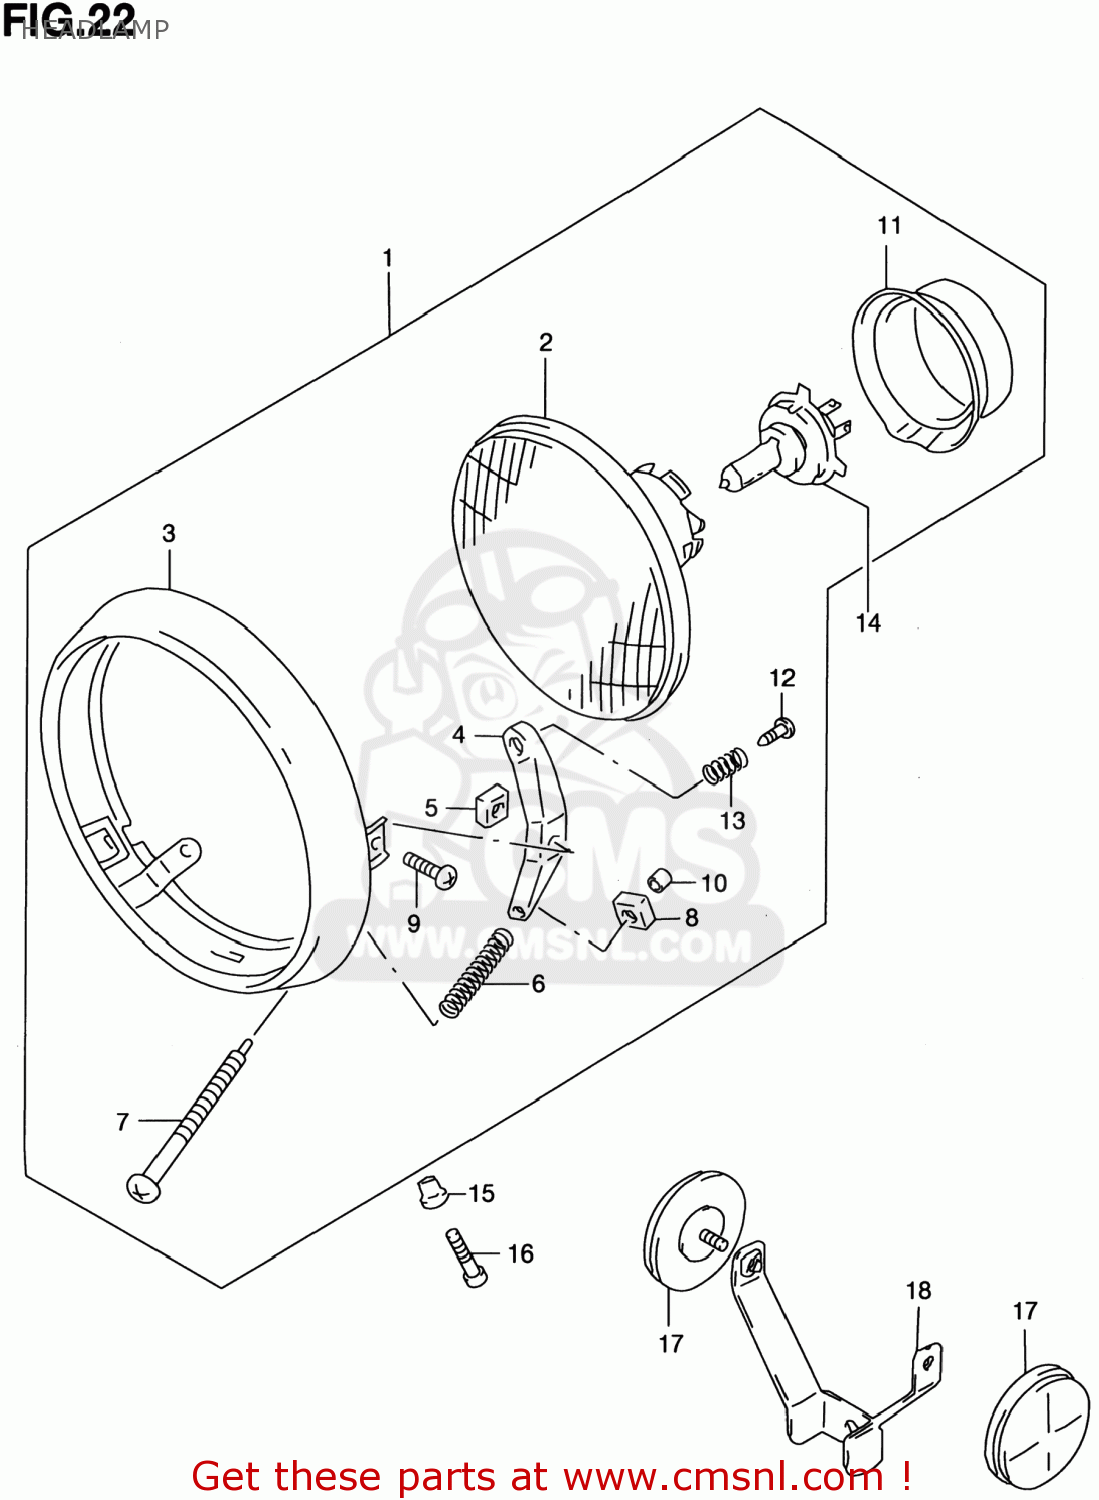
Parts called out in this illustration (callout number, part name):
1	HEADLAMP ASSEMBLY
2	UNIT ASSEMBLY
3	RIM,HEAD LAMP
4	STAY
5	NUT
6	SPRING
7	ADJUSTER SCREW
8	NUT,HEADLAMP ADJUST
9	SCREW
10	CAP,SCREW
11	COVER,SOCKET
12	SCREW
13	SPRING
14	BULB(12V60/55W,H4)
15	SPACER,HEADLAMP
16	SCREW
17	REFLEX REFLECTOR,RR
18	BRACKET,FR SIDE RR
